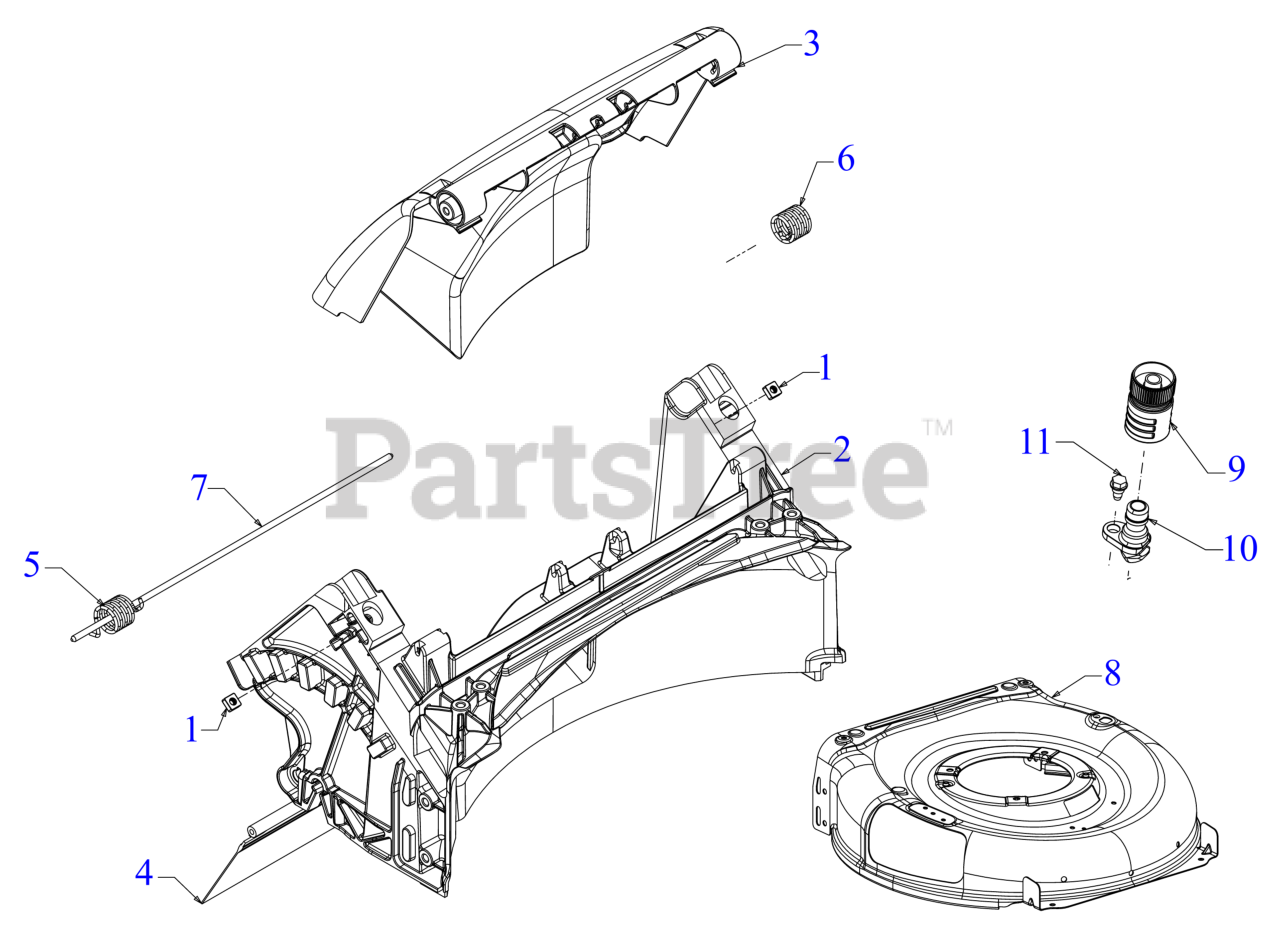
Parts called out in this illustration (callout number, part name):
1	SQUARE NUT 1/4-20
2	REAR DOOR ASSEMBLY
3	REAR DOOR ASSEMBLY
4	TRAILSHIELD
5	TORSION SPRING (RH)
6	TORSION SPRING (LH)
7	REAR DOOR PIVOT ROD
9	WATER NOZZLE ADAPTER
10	DECK WASH NOZZLE
11	SHOULDER SCREW 1/4-20 x .50
